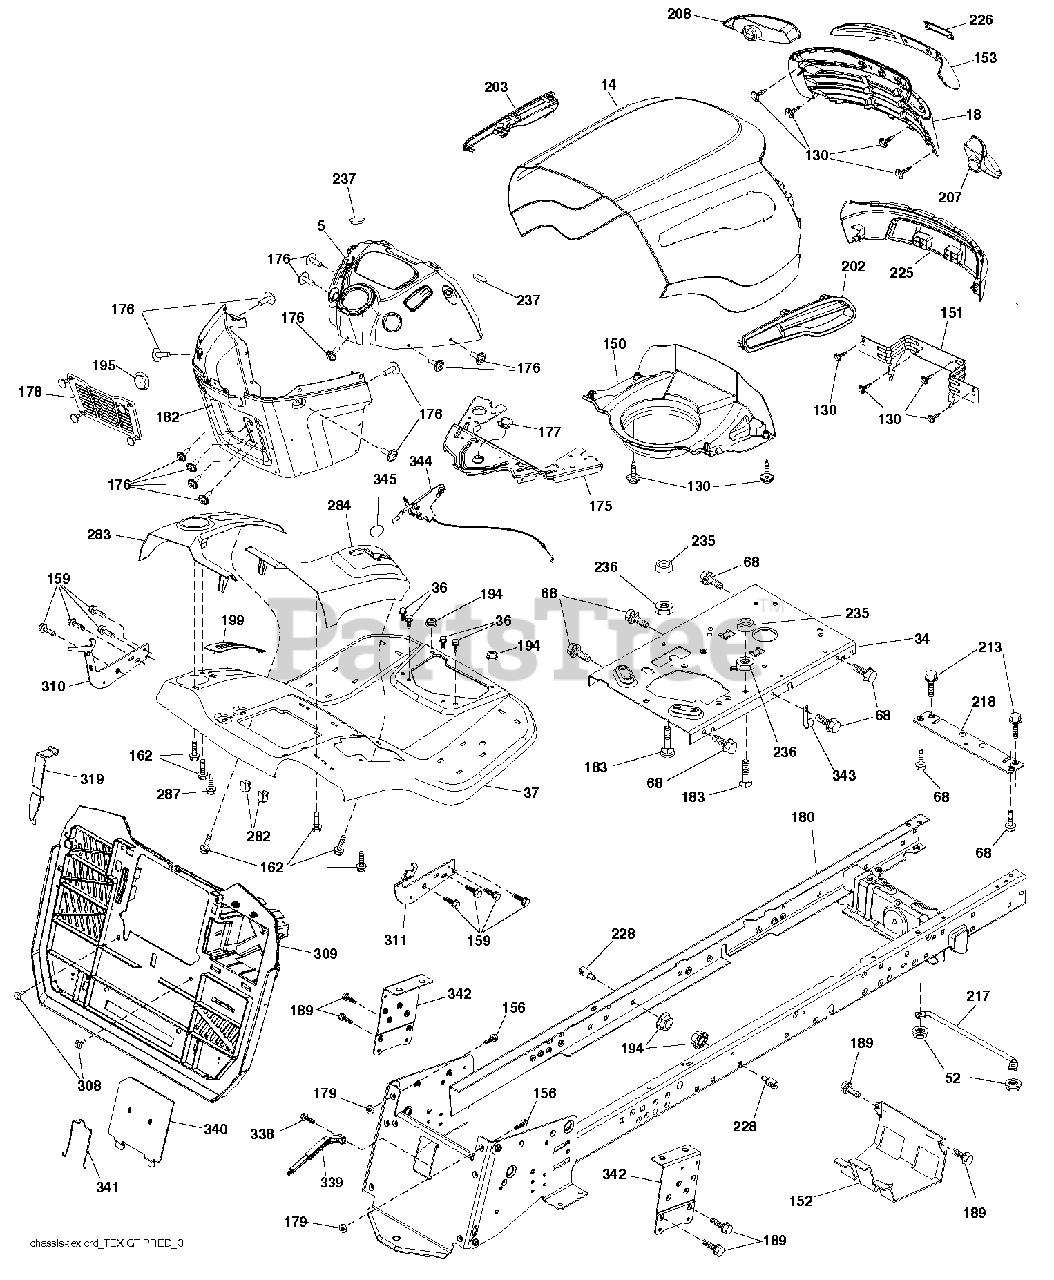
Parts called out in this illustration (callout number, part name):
36	SCREW 5/16"
52	LOCKNUT
68	SCREW LT
130	SCREW.#10 X 0.750.BOS THREAD
152	SHIELD BROWNING
156	BOLT
159	SCREW, 3/8-16X3/4
162	SCREW.HI-LO.CONSOLE
175	PLATE.CROSSMEMBER.HUSQ
176	SCREW.#10-24X5/8.RN.QU
177	BUSHING,STEERING
178	CARGO.ASM.NET.TXGT.W/C
183	BOLT.5/16-18X1-1/4 FULL THD
189	SCREW
194	NUT LOCK HEX FLANGE 5/16-18
195	PLUG.HOLE.DASH.LOWER.12V.BLK
213	BOLT
217	ROD.PIVOT.HOOD
218	X-PIECE.HOOD.STOP.NON/
228	STUD.FASTNER.W/ANTI-ROTATE
235	SPACER FENDER
236	NUT.CENTERLOCK.5/16-
237	PLUG.MOUNT.CARGO.BLK
282	CLIP.RETAINER.CONSOLE.LT.HUSQ
308	BOLT, 5/16-18 X 1 3/4
